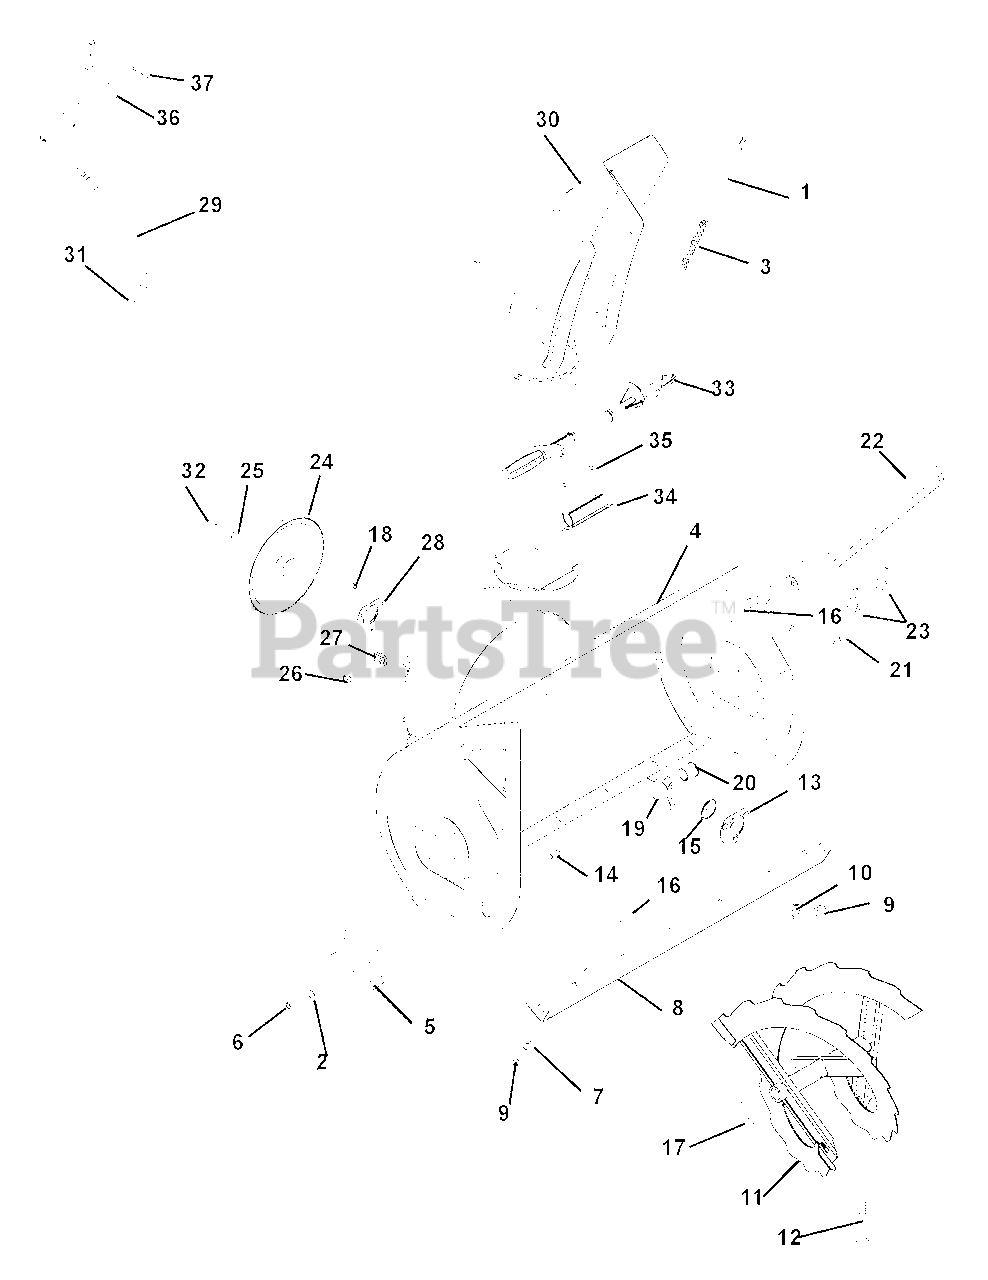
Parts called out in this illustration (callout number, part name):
1	ROD, DEFLECTOR CAP
2	@WSHR-FL-STL.438X1.00X.083 YWZ
3	SG-COMP .08X.40X6.50 14#/IN
4	HOUSING, BLOWER-26" W/DECAL
4	HOUSING, BLOWER-28" W/DECAL
4	HOUSING, BLOWER-32" W/DECAL
5	RUNNER, SKID SHOE-1/2" FLANGE
5	SKID SHOE, REVERSIBLE - ORANGE
6	@NUT-LK-CTR .38-16 YWZC
7	@WSHR-FL-STL.438X1.00X.083 YWZ
7	@WSHR-FL-STL.38X.875X.083 YWZC
8	BLADE, SCRAPER-26"
8	BLADE, SCRAPER-28"
8	BLADE, SCRAPER-32"
9	@NUT-LK-CTR .31-18 YWZC
10	FTG-LUBE .25-28X.256 YWZC
11	RAKE, LH-26"(1 ID X 15.75 OD)
11	RAKE, RH-26" (1 ID X 15.75 OD)
11	RAKE, LH-28" (1 ID X 15.75 OD)
11	RAKE, RH-28" (1 ID X 15.75 OD)
11	RAKE, LH-32" (1 ID X 15.75 OD)
11	RAKE, RH-32" (1 ID X 15.75 OD)
12	SHEAR BOLT SERVICE ASSEMBLY
13	BEARING FLANGE
14	@BLT-RDHDSHSQNK.38-16X1.0 G5YZ
15	BRG-BALL .876 X 1.750 X .50
16	@BLT-RHDSSQNK .31-18X.75 G5YZ
17	WSHR-FL-STL 1.010X1.505X.062YZ
18	@NUT-LK-CTR .25-20 YWZC
19	BUSHING, RAKE SHAFT 1"
20	BSHG-FLG, SPLIT NYLINER 1.0"ID
21	@SCR-TAP .25-20X.50 HWH TR YWZ
22	CUTTER, DRIFT
23	KNOB - WING .312-18 UNC
24	PULLEY, 4L W/HUB, .87 X 8.5
25	WSHR-LK .312X.097 HVY YWZC
26	BLT-SERHFWH .38-16X.75 YWZC
27	NUT-RTNR .375-16X.37
28	BEARING FLANGE
29	CABLE, DEFLECTOR
30	CHUTE, DISCHARGE-W/DEFLECTOR
31	J-CLAMP
32	BLT-HEX .31-24X.75 YWZC GR5
33	DEVICE, SNOW CLEAN OUT
34	MOUNT, SNOW CLEAN OUT
35	RVT-POP .187X.45 DOME SS FBF64
36	@WSHR-FL-STL.281X.62X.065 YWZC
37	PIN-HAIR INT .06X.18X.77
